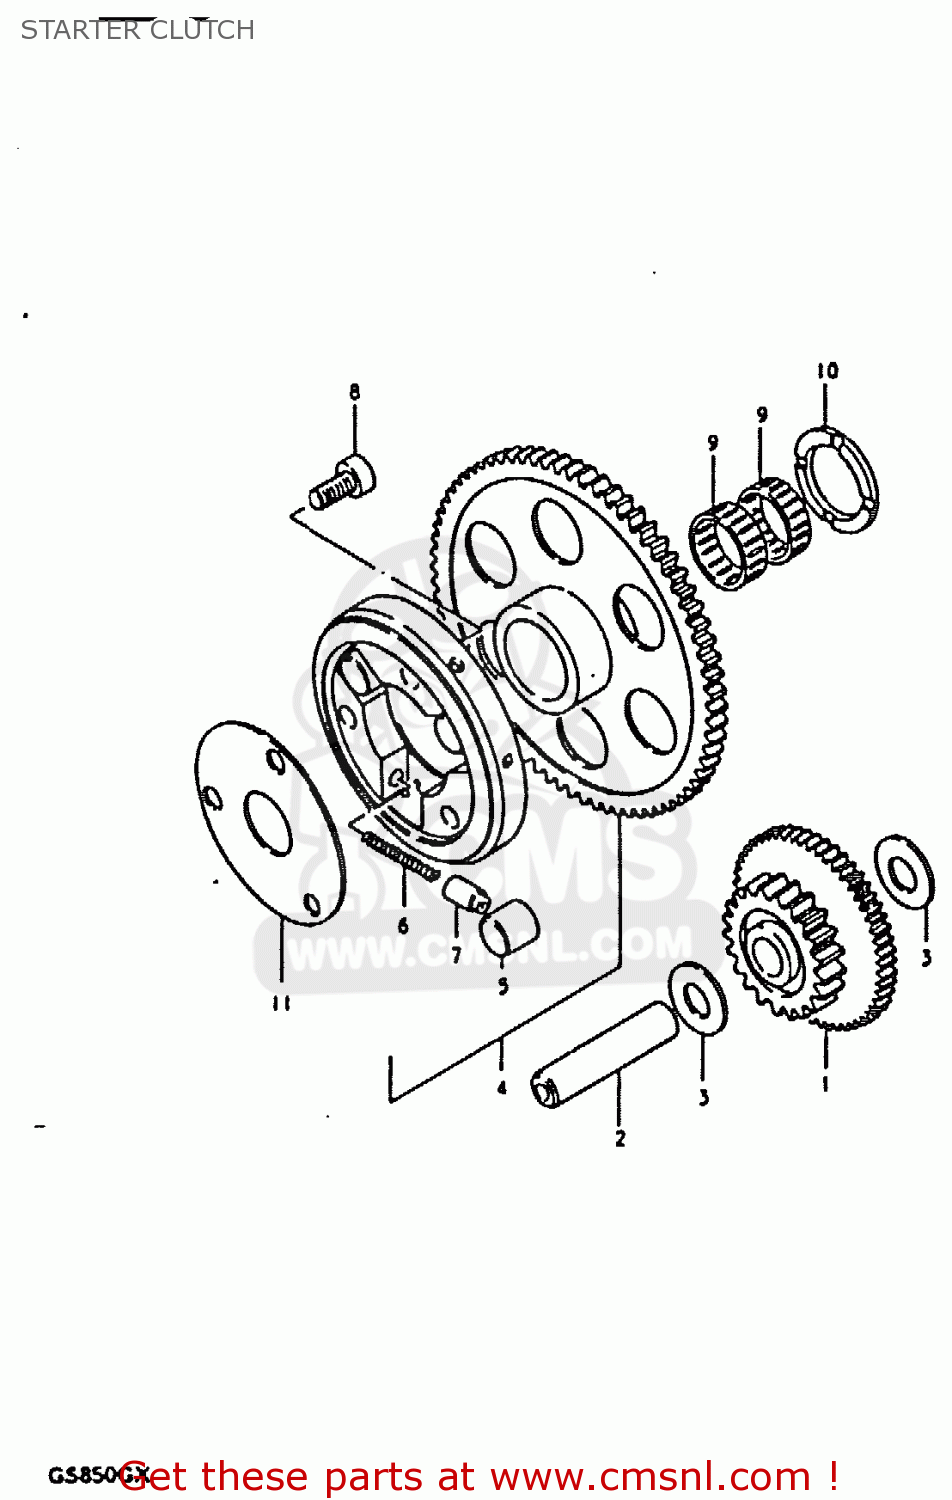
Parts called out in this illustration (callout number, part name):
1	GEAR,STARTER IDLE
2	PIN(7.4X13X56)
3	WASHER(13.3X25X0.85)
4	CLUTCH SET,STARTER
5	ROLLER(15X13)
6	SPRING
7	PIECE,PUSH
8	BOLT
9	BEARING
10	WASHER(25X38X2.5)
11	SHIM,STARTER CLUTCH HUB
